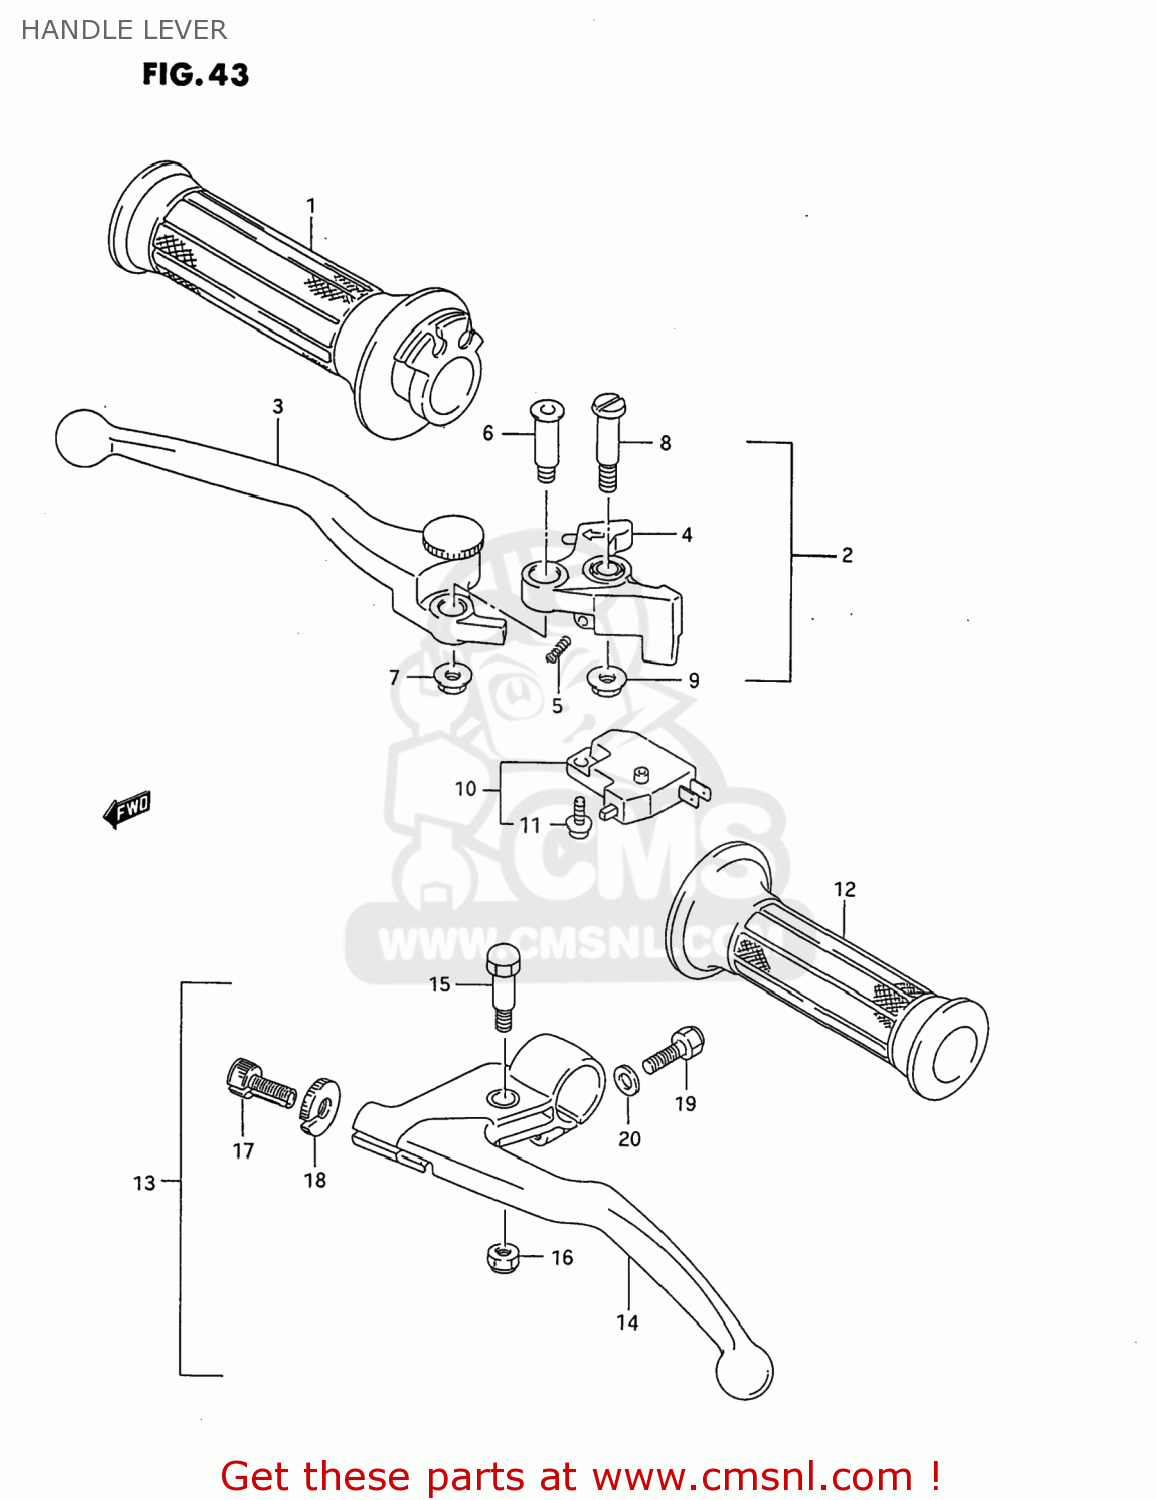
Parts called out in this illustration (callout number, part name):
1	GRIP,THROTTLE
2	LEVER ASSEMBLY,BRAKE
3	LEVER,ADJUST
4	KNOCKER
5	SPRING
6	BOLT,LEVER
7	NUT
8	BOLT,LEVER PIVOT
9	NUT
10	SWITCH ASSEMBLY,STOP
11	SCREW
12	GRIP,L
13	LEVER ASSY,CLUTCH
14	LEVER,CLUTCH
15	BOLT,LEVER PIVOT
16	NUT
17	ADJUSTER,CABLE
18	NUT,CABLE ADJUSTER LOCK
19	BOLT
20	WASHER
